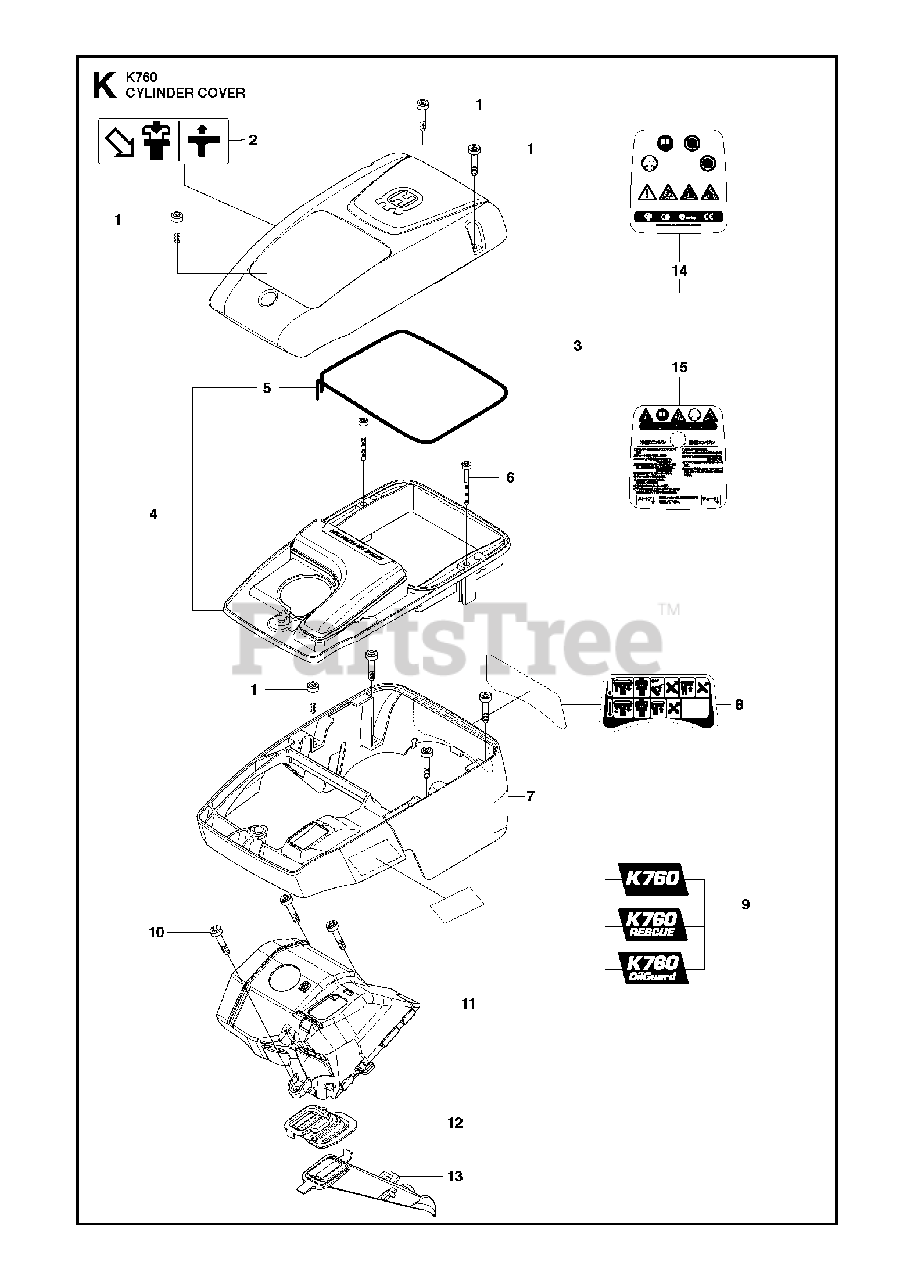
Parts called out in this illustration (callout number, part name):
1	SCREW ITXSCM
3	FILTER COVER ASSYincl. 14
4	FILTER HOLDER ASSYIncl. 5
4	FILTER HOLDER ASSYOIL GUARD
5	SEALING STRIP
6	SCREW ITXSCM
7	CYLINDER COVER
9	DECALOil Guard
10	SCREW ITXSCM
12	BELLOWS
